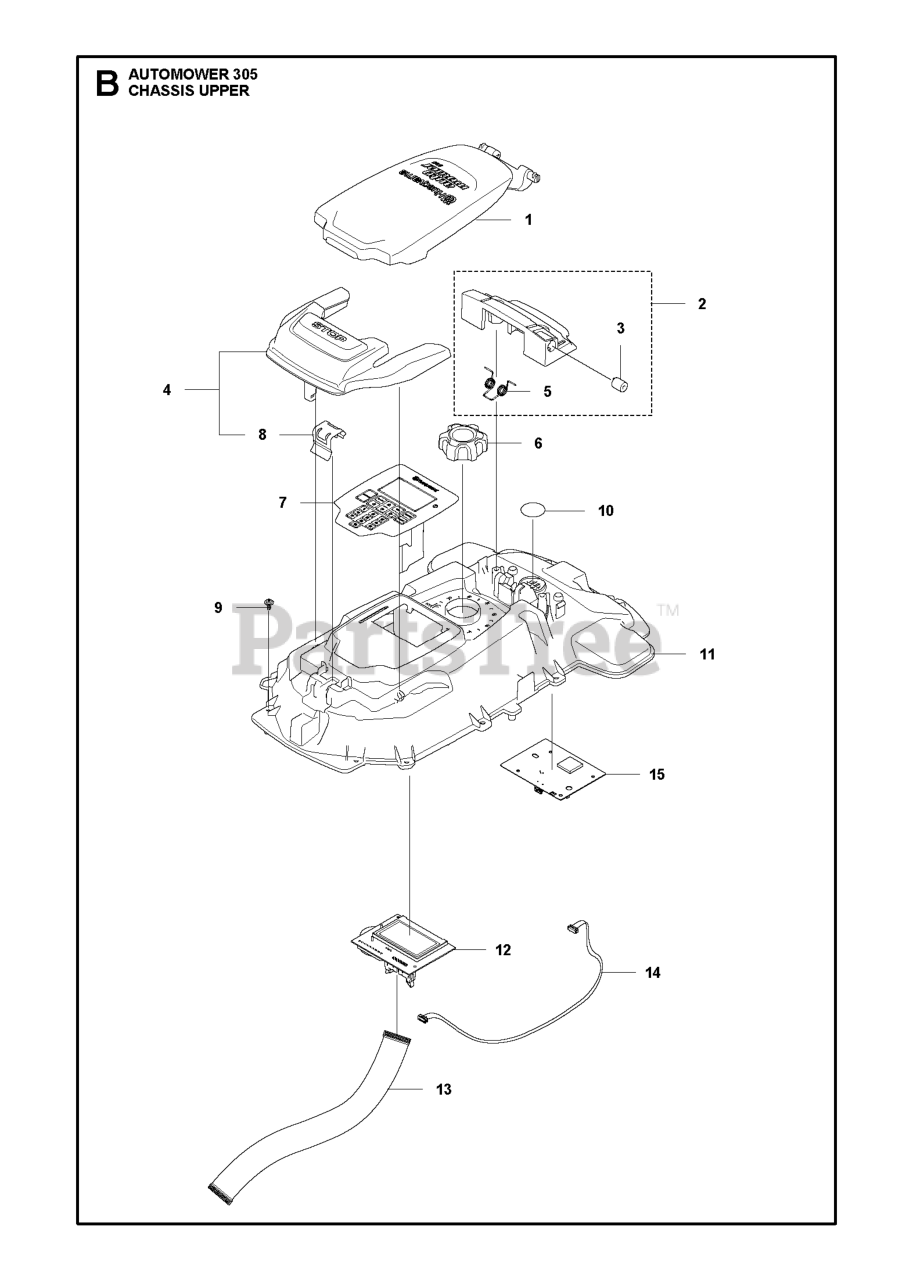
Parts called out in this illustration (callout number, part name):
2	SUPPORT FRONT ASSY
3	DAMPER TORSION FA 1100
5	TORSION SPRING DT=1,3MM
6	KNOB HEIGHT ADJUSTMENT
8	SPRING BUTTON STOP DELTA SEAL
9	SCREW ITXPANT
10	KIT AIR FILTER KIT 305 - 10 PC
13	CABLE ASSY HMI CABLE L=185MM
14	Wires
15	GPS MODULE 2G + 3G
